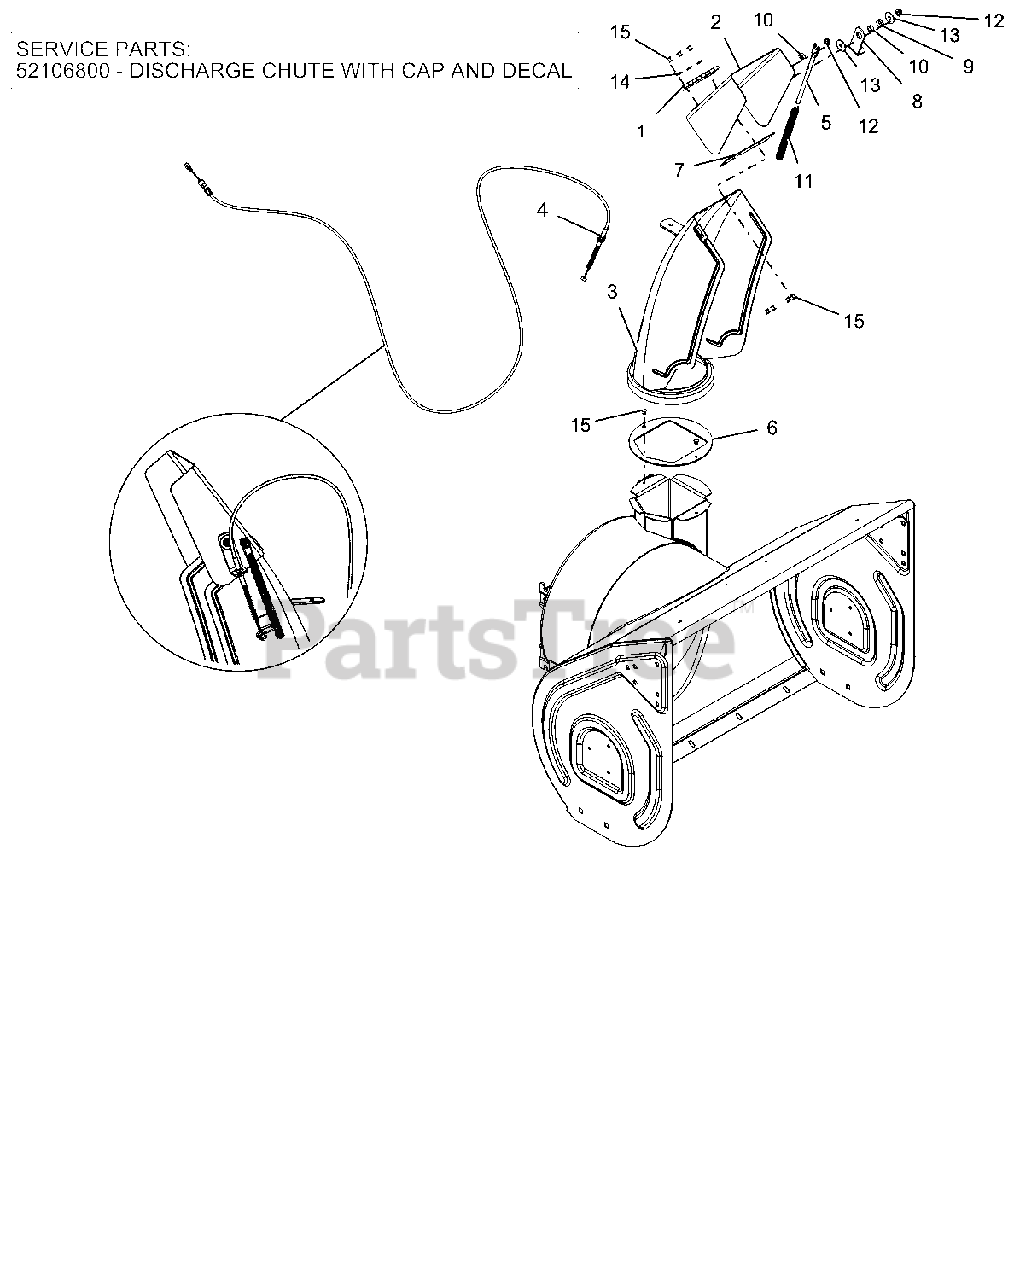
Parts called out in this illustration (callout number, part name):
2	CAP,LARGE,REMOTE
3	CHUTE,DISCHARGE,NOTCHED,QT
4	CABLE, DEFLECTOR - DELUXE
5	ROD, DEFLECTOR CAP
6	BAFFLE, DISCHARGE NECK
7	CAP SEAL 5.50
8	BRACKET, CABLE ANCHOR
9	BUSHING, POLYLINER-.50 SNAPIN
10	BSHG-SLV .265X.500X.219
11	SG-COMP .08X.40X6.50 14#/IN
12	@NUT-LK-CTR-FLG .25-20 YWZC
13	WSHR-FL-STL .281X1.000X.063
14	WSHR-FL-STL .196X.500X.06 YZ
15	RVT-POP .187 YZ
16	KIT, DISCHARGE CHUTE W/DEF QT2
